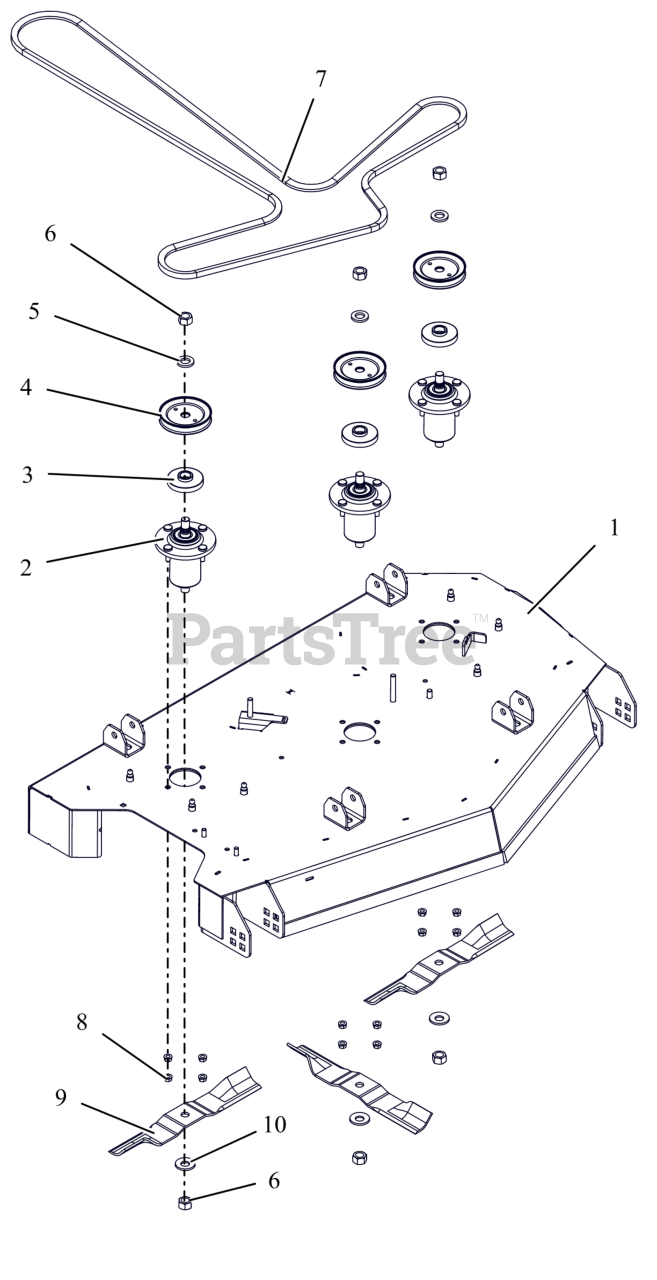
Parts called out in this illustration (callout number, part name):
1	KIT-GRAVELY DECK 42" W/ DECALS
2	ASM, ALUMINUM SPINDLE SUB
3	SHIELD, DUST
4	PULLEY-V-4.00 ODX.625SPLINE ID
5	SPCR- .735 X 1.313 X .165
6	NUT-STD .625-18 ZCC
7	V-BELT, HA-WRAPPED
8	NUT,LK-CTR-FLG .31-18 GF ZCC
9	BLADE- 14.5" MOWER (HI-LIFT)
10	WSHR-BLVL .669X1.535X.138
